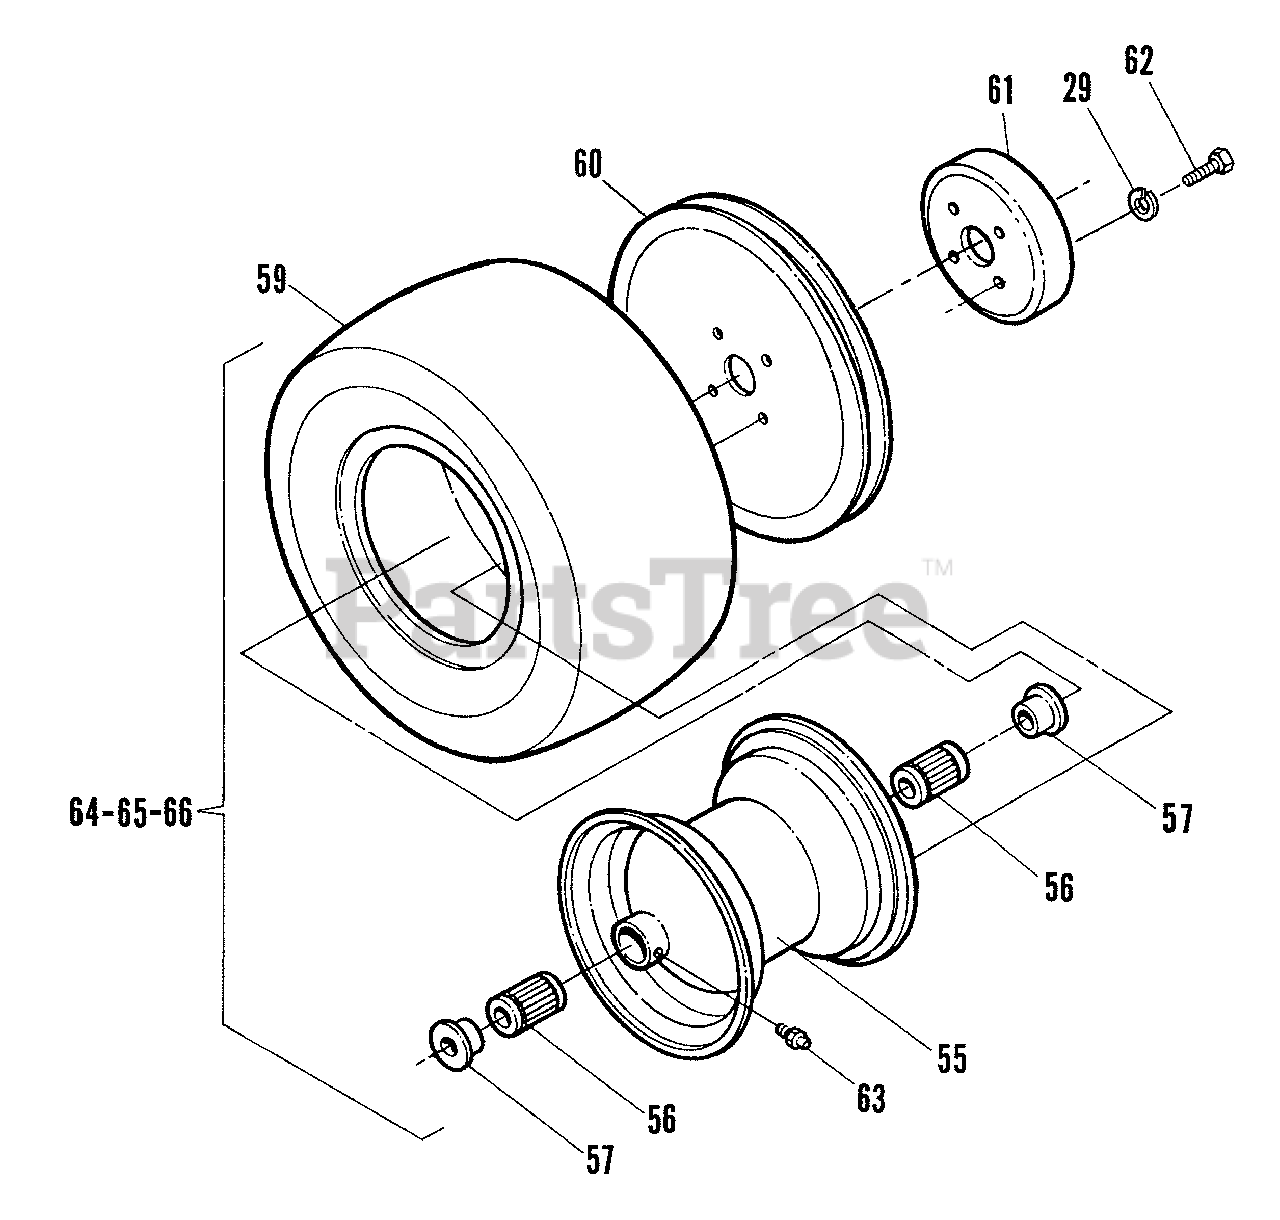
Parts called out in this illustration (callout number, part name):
29	WASHER, 3/8" Split Lock
55	WHEEL, w/Flange Assembly (36" & 48")
56	BEARING, Roller (32")
57	BUSHING, Flange
59	TIRE, 2 Ply Turfmaster (32")
61	DRUM, Brake
62	SCREW, 3/8-24 x 5/8" Hex Head Cap, Grade 5
63	FITTING, 1/4-28 Grease
64	WHEEL, w/Sheave & Drum Assembly (32")
65	TIRE ASSEMBLY, w/Bearings (36" & 48")
66	TIRE ASSEMBLY (32")
